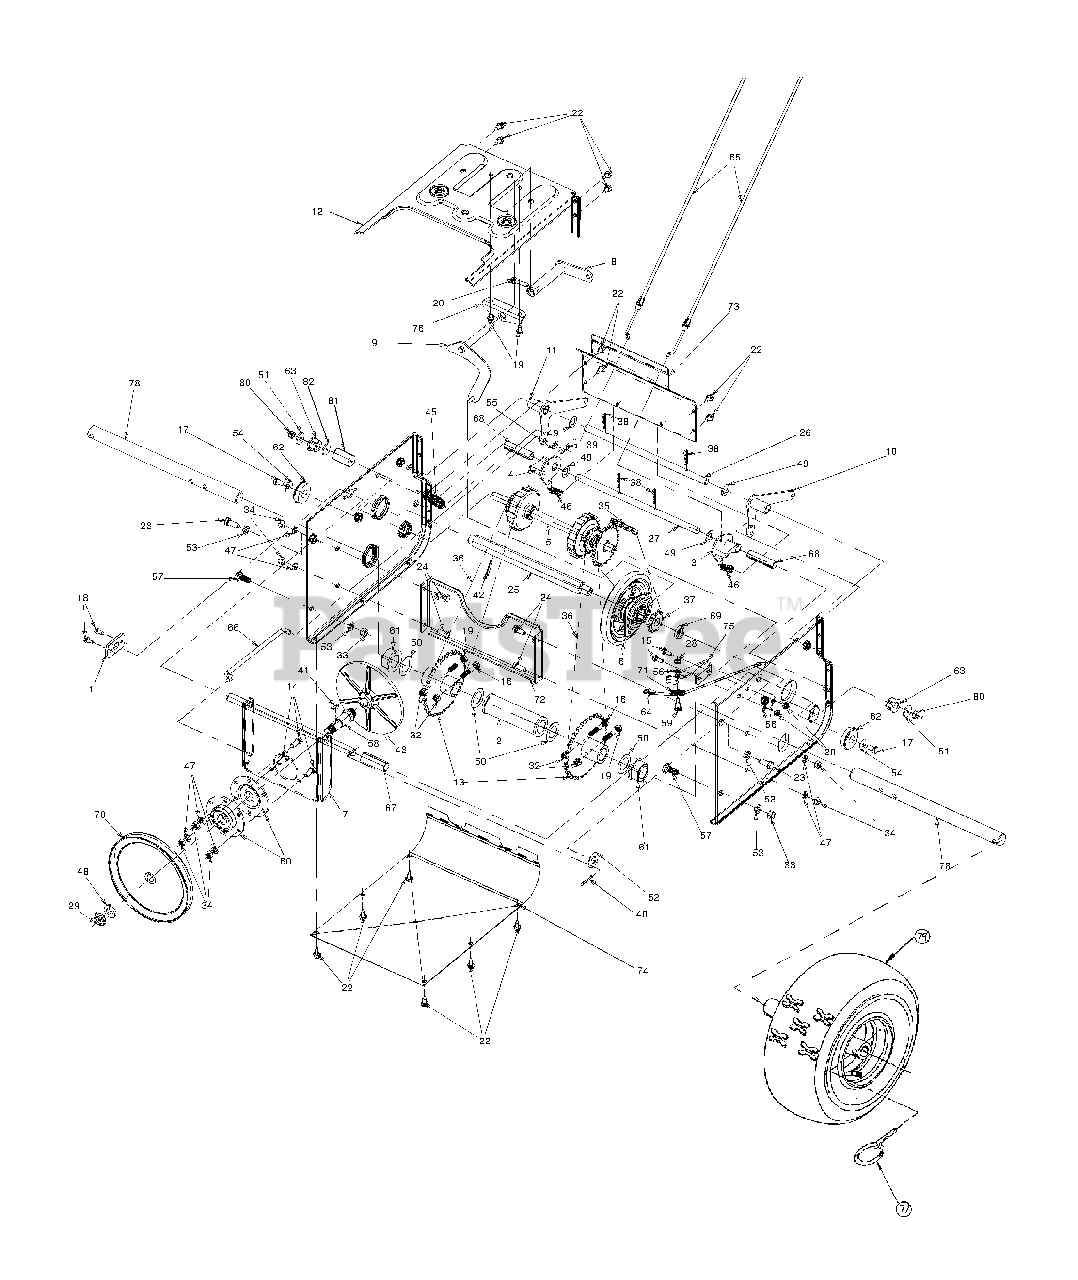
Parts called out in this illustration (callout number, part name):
1	Pivot Axle Brkt. .63 Hole - Zinc
2	Bush Asm slev
3	Dogg Asm Dr Lh
4	Dogg Asm Dr Rh
5	Shf Asm Dr
6	Whl Asm Brg 6.0 OD Friction
10	Brkt Asm Actr Auger
14	Hex Scr 5/16-18 x .75
15	Hhcs 1/4-28 .625 Gr5 std
16	Hex Scr 5/16-18 x 2.00
17	Hhcs 5/16-18 x .625 Gr5 Lock
18	Scr TT 1/4-20 x .5 Hxindwsh
19	Hex Scr 5/16-18 2.00 Lg
20	Scr Hexwash 1/4-20 x 2.00
22	Scr Ab 1/4-14 .625 Hxindwsh
23	Hhcs 3/8-16 x .880 Gr5 Std
24	Scr Cap 5/16-18 x .75 Gr 5
25	Shf Dr .875 Hex
26	Shf Sctr
27	Shf Actr Dr
28	Hex Nut 1/4-28
29	Hex Ins Jam L-nut 5/8-18
32	Hex Ins L-nut 5/16-18
33	Hex Nut 3/8-16
34	Nut Hex 5/16-18 Gd 5
35	#41 Chain 1/2 Pitch x 36 L
36	#420 Chain 1/2 Pitch x 40 L
37	Spkt 10t #41 x .500
38	Internal Cot-pin 1/2 Dia
39	Intern Cot-pin 5/16 Dia
40	Cotter Pin 1/8 Dia x 1
41	#61 Hi-pro-key 3/16 x 5/8
42	Spring Pin Roll 5/32
43	Aluminum Drive Plate
45	Idler Extension Spring
46	Extension Spring
47	Lock Washer 5/16
48	Lock Washer 5/8
49	Wash Fl .531 ID x .930 OD x .05
50	Wash Fl 1.03 ID x 1.62 OD
51	Wash Flt 1/4 ID x .930 OD x .12
52	Wash Flt .640 ID x 1.24 OD x .06
53	Lock Washer 3/8 Heavy
54	Bell Wash .345 ID x .88 OD
55	Fl-wash Sae .34 x .68 .062
56	Lock Washer 1/4
57	Shld Scr .498 Dia x .340
58	Drive Plate Spindle
59	Scr Shldr .340 D. 1/4 Ab
60	Asm Brg Hsg
61	Flange Brg Pm W/flts 1.0
62	Ball Bearing W/snap Ring
63	Brg Hex Flange x .564 ID
64	Cb Idlr Auger
65	Cbl Strg
66	Rod Clu Dr
67	Spcr Splt .64 x .77 x 2.1
68	Split Spacer 1/2 x 5/8 x 2.44
69	Spcr .675 ID x 1.00 OD x .23
70	1/2 V-pulley .62 ID x 7.5
71	Cable Guide Roller
77	Klik Pin Assy Danuse
78	Axle 1.0 OD x 14.1 Lg
80	Hex Jam Nut 3/8-24 Thd.
81	Spacer
82	Fl-Washer
